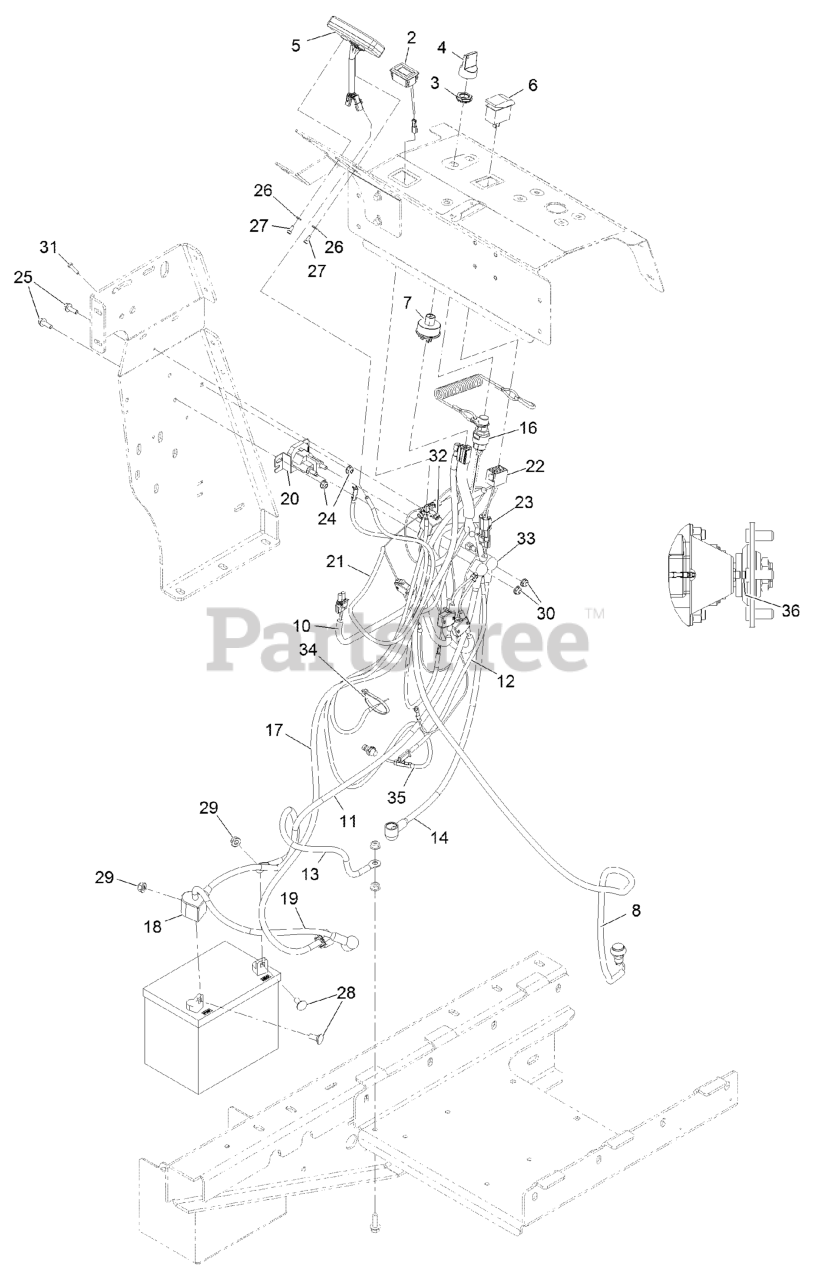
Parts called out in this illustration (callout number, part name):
2	METER-TACH/HOUR
3	NUT-SWITCH, KEY
4	KEY-UMBRELLA
5	HEAD ONLY, STRIKER
6	SWITCH-ROCKER
7	SWITCH-IGNITION
8	Switch-Push Button
10	Harness, Main
11	CABLE-POSITIVE
12	Wire-Solenoid
13	CABLE-GROUND
14	CABLE-POSITIVE
16	SWITCH-OP
17	Harness, Alternator
18	Insulator-Battery
19	CABLE-POSITIVE
20	Solenoid-Starter
21	HARNESS-STRIKER
22	CONNECTOR-CARLING, 8F
23	Connector-Wp,2M
24	Nut-Hex Flange
25	Screw-HHF
26	WASHER-FLAT
27	SCREW-HSH
28	SCREW-CARR
29	Nut-Hex Flange
31	SCREW-HH
32	Nut-Hex Flange
33	INSULATOR-SOLENOID
34	TIE-CABLE
35	Cable-Trail Tech, Sensor
36	MAGNET, SPEEDOMETER
